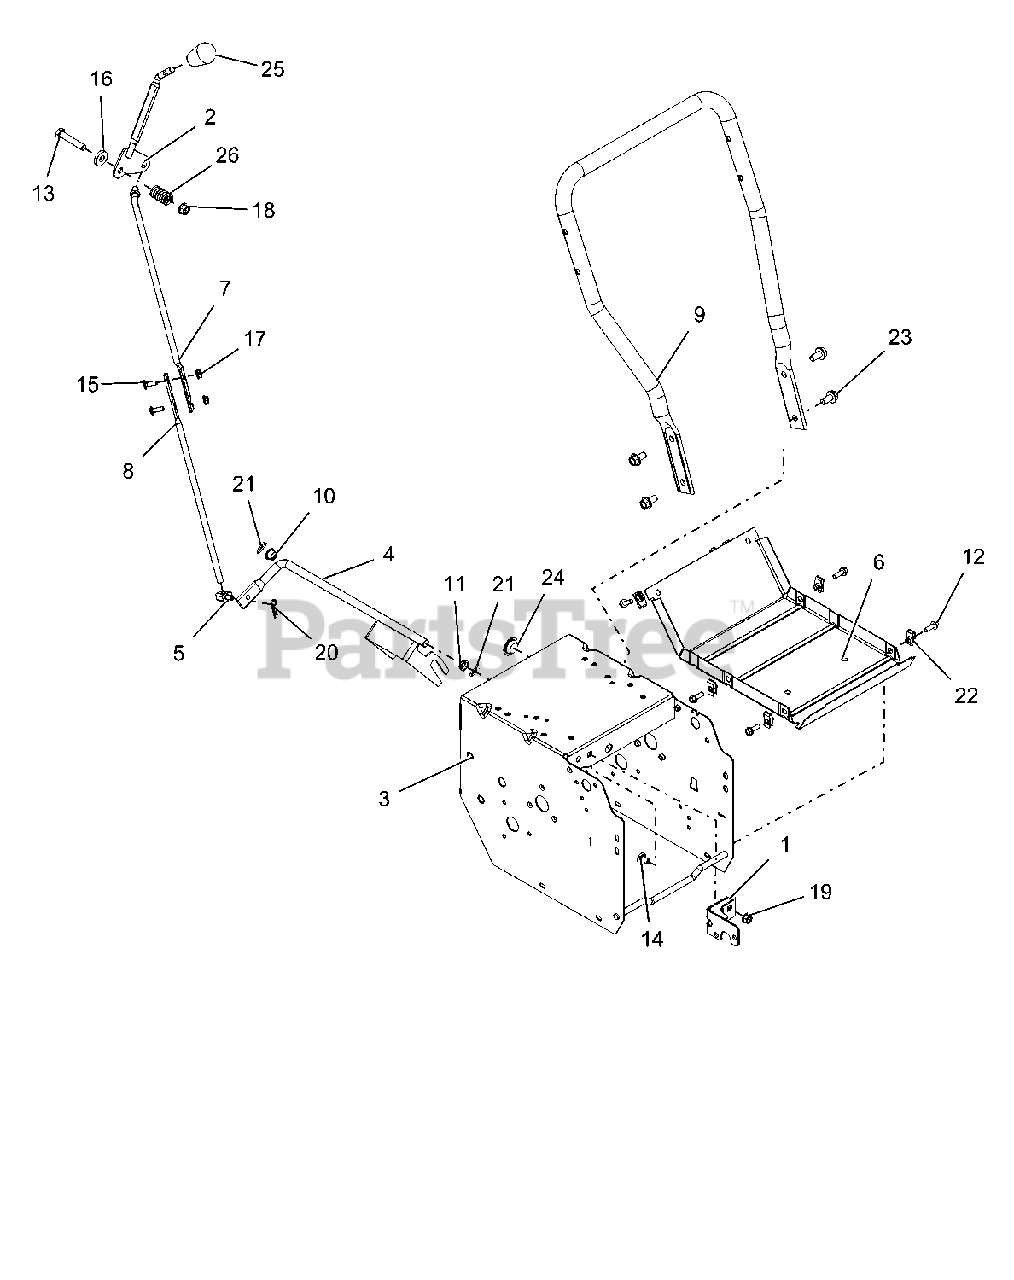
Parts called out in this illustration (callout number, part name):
1	WLDMT, FRAME BRKT
2	LEVER, CONTROL - SHIFT (WELDMENT)
3	WELDMENT, FRAME - DELUXE 16"
4	WLDMT, SHIFT FORK
5	PIVOT, SHIFT ROD .375-16 (TRUNN)
6	COVER, BOTTOM
7	ROD, SHIFT UPPER
8	ROD, SHIFT - LOWER (BLACK)
9	HANDLEBAR, LOWER - SM DELUXE
10	BUSHING, POLYLINER - .50 SPLIT
11	BSHG, POLYLINER - .50 SNAP-IN
12	BLT-HEX .25-20X.75 HWH YWZC GR5
13	BLT-HEX .38-16X2.00 GR5 YWZC
14	BLT-RHDSSQNK .31-18X.62 G5YZ
15	BLT-RDHDSQNK .25-20X.75 G5 YWZC
16	WSHR-FL-STL .406X1.00X.188 YWZC
17	NUT, LK-CTR-FLG .25-20 YWZC
18	NUT, LK-TOP-FLG .38-16 YWZC
19	NUT, LK-TOP-FLG .312-18 YWZC
20	PIN, HAIR INT .08X.18X1.18 YWZC
21	CLIP, SPRING
22	NUT, RTNR .25-20 X .56
23	BLT-SERHFWH .38-16X.75 YWZC
24	PLUG, HOLE - .875"
25	KNOB, SOFT TEARDROP, PUSH-ON BLK
26	SPRG, COMPRESSION
